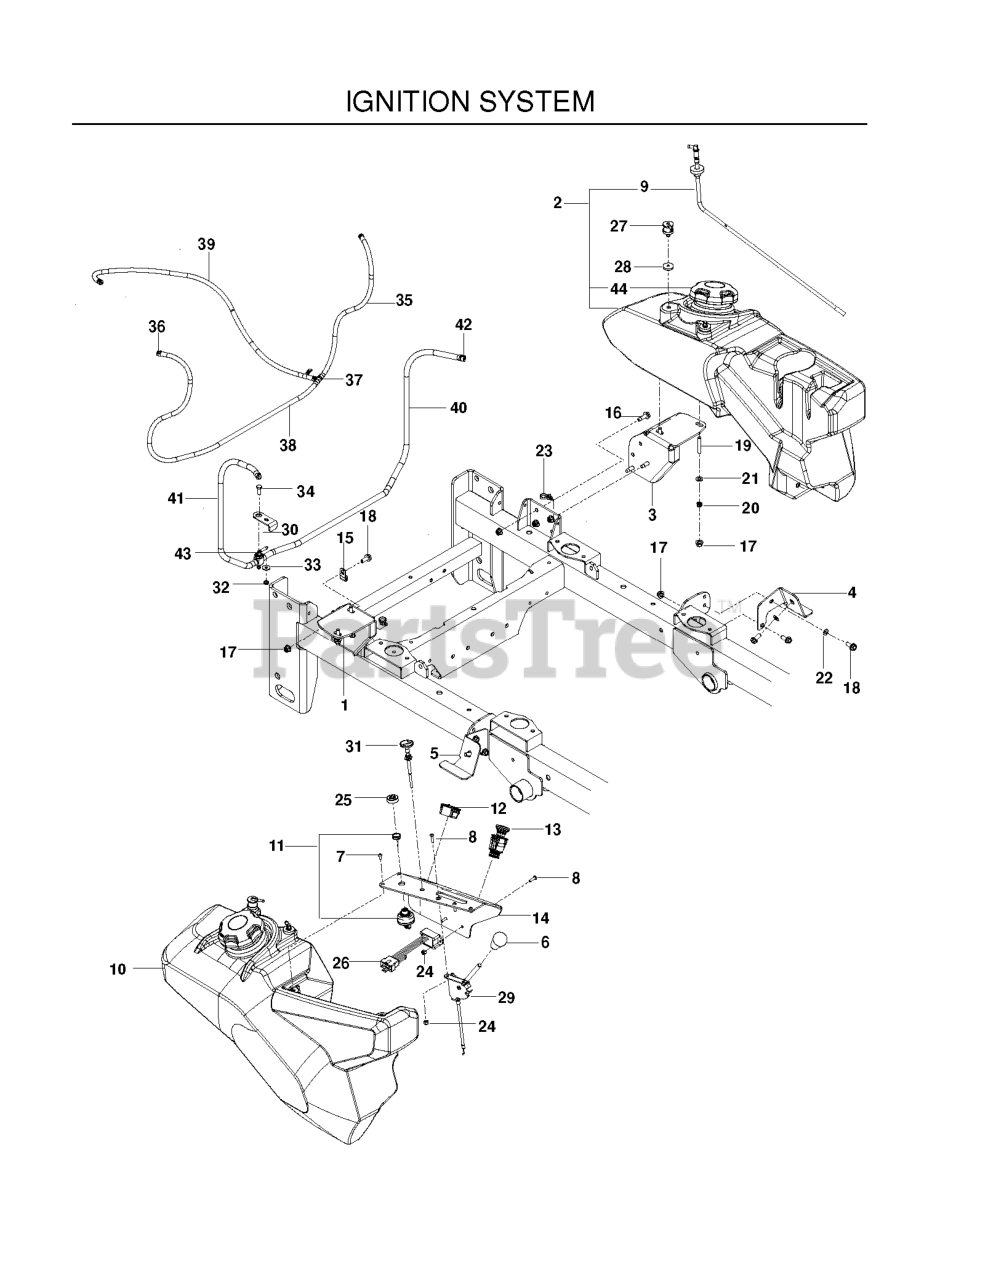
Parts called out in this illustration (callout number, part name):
1	MOUNT, RT TANK, BLK
2	LT FUEL TANK ASM EPA
3	MOUNT, LT TANK, BLK
4	MOUNT, TANK, LT-BLK
5	XX MOUNT, TANK, RT-BLK
6	KNOB - SHIFT
7	SCR #10-24 X 3/8 SKT HD BLK OX
8	SCR #10-24 X .75 SKT HD BLK
9	FITTING, FUEL
10	RT FUEL TANK ASM EPA
11	SWITCH, IGNITION, INDAK
12	HOUR METER
13	SWITCH, PTO 10 AMP
14	PANEL.CONTROL.GAS.GRAY
15	DOUBLE TUBE CLAMP
16	RP BLT 5/16-18 X 1 THRD FORM D
17	5/16-18 NYLOC FLANGE NUT
18	HHFS 5/16-18 X 3/4
19	STUD, 5/16C
21	FLAT WASHER 5/16 SAE
22	WASH 5/16 DISC SPRING ZD
23	TIE WRAP, 8-3/8", W/CLIP
24	NUT 10-24 NYLOC
25	CAP IGNITION NUT
26	TIMER, SEAT
27	VALVE.FUEL.CHECK
28	GROMMET, CHECK VALVE
29	CABLE, THROTTLE, 46"
30	BRACKET,FUEL VALVE, BLACK
31	CABLE, CHOKE, 48"
32	JAM NUT 1/4C (2 2 PW01)
33	WASHER 1/4 FLAT
34	HCS 1/4C X 3/4 HCS
35	HOSE, 3/16" VAPOR, 21"
36	CLAMP, HOSE
37	TEE, FUEL LINE 3/16"
38	HOSE, VAPOR 3/16 X 39"
39	HOSE, VAPOR 3/16 X 30"
40	LINE, FUEL, 22"
41	LINE, FUEL, 38"
42	HOSE CLAMP
43	FUEL VALVE
44	CAP, FUEL
